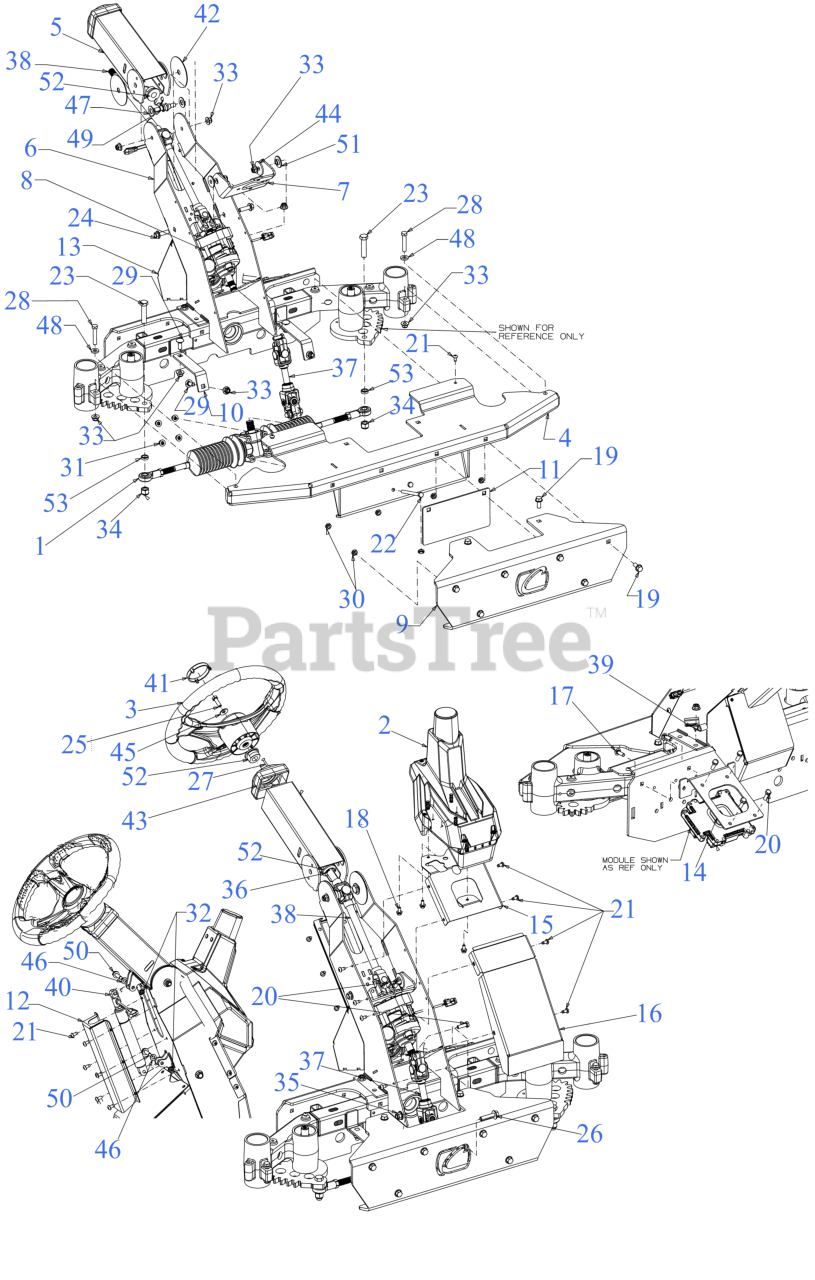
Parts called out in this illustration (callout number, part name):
1	STEERING GEARBOX
2	GPM ASSEMBLY
3	STEERING WHEEL
6	TILT COLUMN
7	EPS BRACKET
8	POWER STEERING (W/MDL & HARN)
8	EPS CONTROL MODULE
8	POWER STEERING ASSEMBLY
8	HARNESS EPS
9	FRONT BUMPER UPPER COVER
13	EPS COLUMN COVER
14	POWER STEERING BRACKET
15	GPM BRACKET
16	COLUMN COVER (LOWER)
17	CARRIAGE BOLT 5/16-18 x 1.00
18	SCREW 1/4-20 x .50 GR5
19	SCREW 3/8-16 x .875 GR5
20	SCREW M8-1.25 x 25 GR8.8
21	SCREW 1/4-20 x .5
22	SCREW 5/16-18 x 4.00 GR5
23	SCREW 1/2-20 x 2.25
24	SCREW 3/8-16 x 1.25 GR5
25	SCREW 5/16-18 x 1.00 GR5
26	HEX FLANGE BOLT M10-1.50
27	SCREW #10-16 x 1.25
28	SCREW 3/8-16 x 2.0 GR5
29	CARRIAGE BOLT 3/8-16 x 1.00 GR5
30	JAM LOCK NUT
31	FLANGE LOCK NUT 5/16-18
32	FLANGE LOCK NUT
34	HEX NUT 1/2-20 GR8 NYLON
35	HEX FLANGE NUT M10-1.50
37	LOWER STEERING SHAFT
38	STEERING SHAFT (UPPER)
39	J TYPE CLIP
40	TILT STEERING DAMPENING CYLINDER
41	STEERING WHEEL CAP
42	COLUMN PLATE
43	STEERING COLUMN COVER
44	FLAT WASHER .390x1.500x.134
45	BELL WASHER .337 X.867 x .057
46	FLAT WASHER
47	TEFLON WASHER .570x1.120x.062
48	FLAT WASHER
49	SHOULDER SCREW .498 DIA x .340
50	SHOULDER SCREW
51	SHOULDER SPACER
52	FLANGE BEARING
